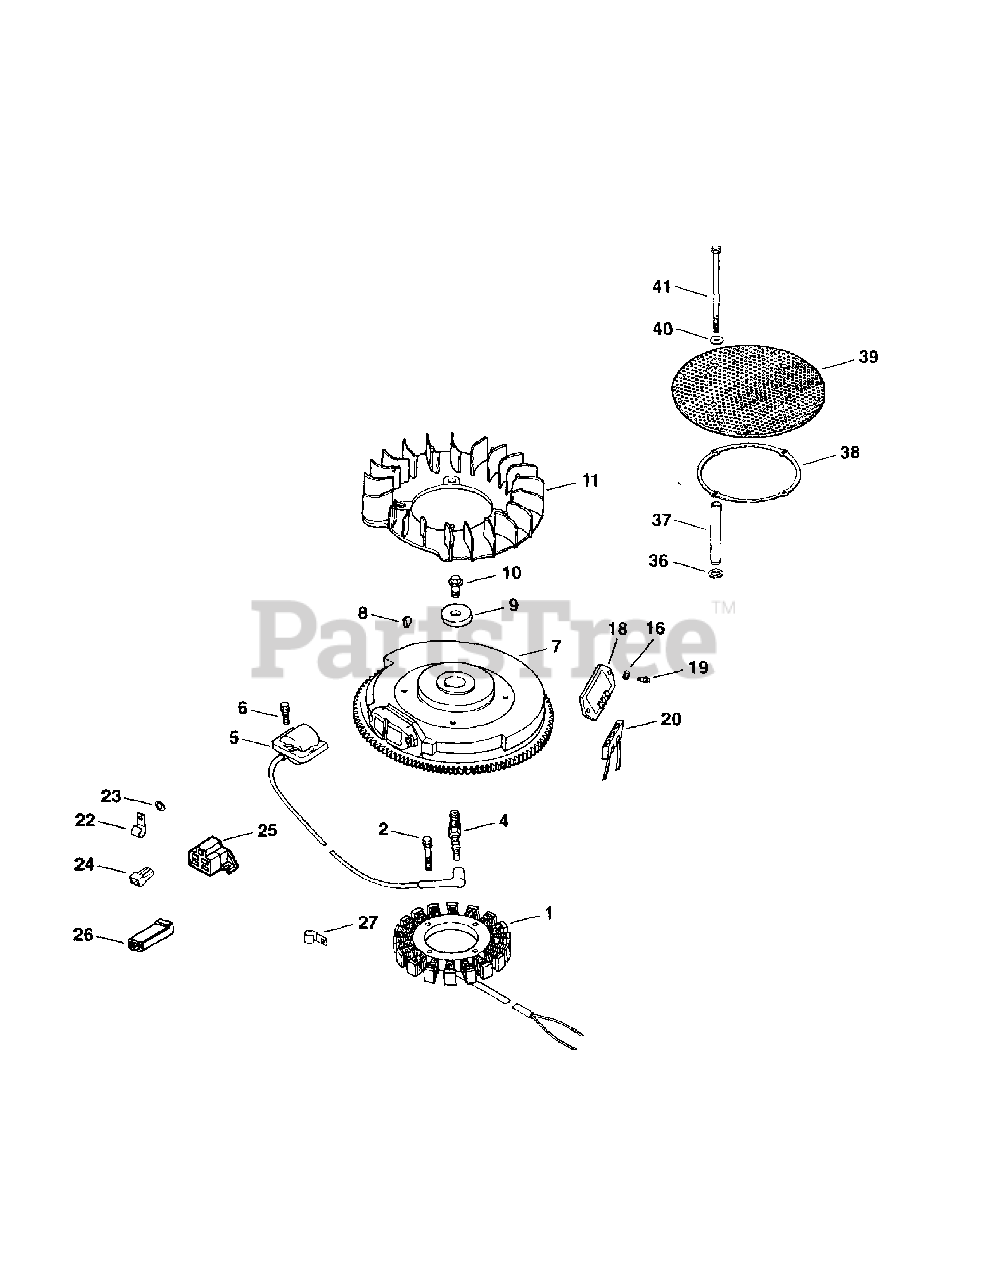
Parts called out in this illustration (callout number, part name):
1	Stator (15 Amp)
2	Screw, Hex Cap
4	Spark, Plug
5	Module, Ignition
6	Screw, Hex Flange
9	Washer, Plain 3/8"
10	Screw, Hex Flange
11	Fan
16	Washer, Plain 1/2"
18	Rectifer-Regulator
19	Screw, Hex Flange
20	Connector (3 contact)
23	Washer, Plain 1/4"
24	Connector
25	Connector
26	Connector
27	Clip, Cable
36	Washer, Spring 10mm
37	Spacer, Grass Screen
38	Ring, Support
39	Screen, Grass
40	Washer, Plain
41	Screw, Hex Cap
